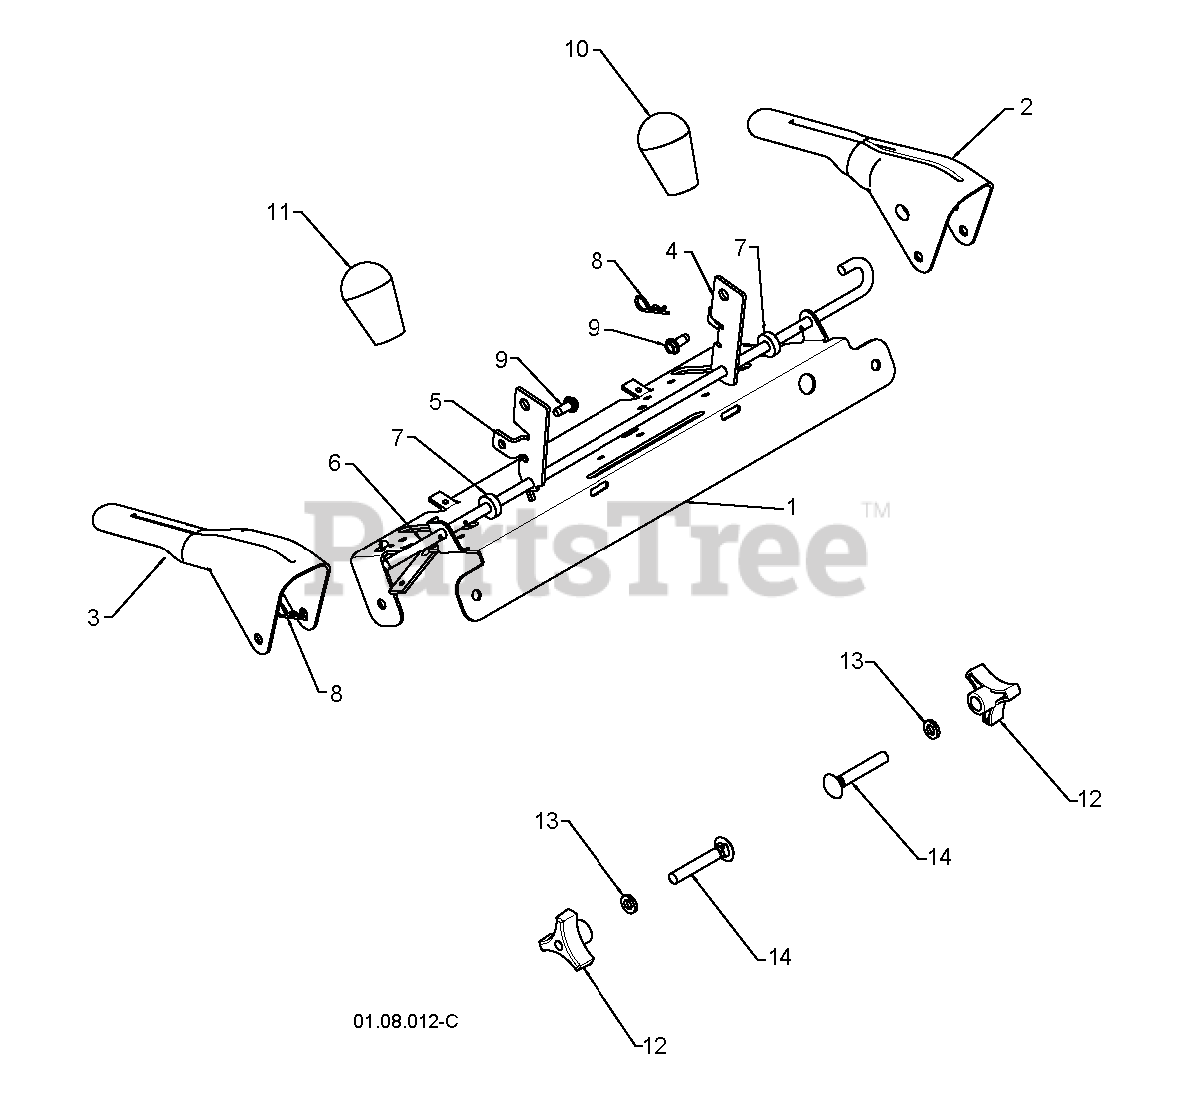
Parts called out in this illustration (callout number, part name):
1	PANEL.CONTROL.PNT.BLACK
2	LEVER.CONTROL.LH.BLACK
3	LEVER.CONTROL.RH.GREY
4	ARM.TRACTION.ROD.YZ
5	ARM.IMPELLER.ROD.SNOW
6	BAIL.CONTROL.INTERLOCK
7	SPACER.CONTROL.LEVER
8	SPRING RETAINER
9	SCREW 14-20 X 5/8
10	KNOB LEVER, BLACK
11	RED KNOB SHIFTER
12	KNOB.HANDLE.3/8.TRI-POINT.BLAC
13	WASHER
14	BOLT 3/8-16 X 2-1/4
